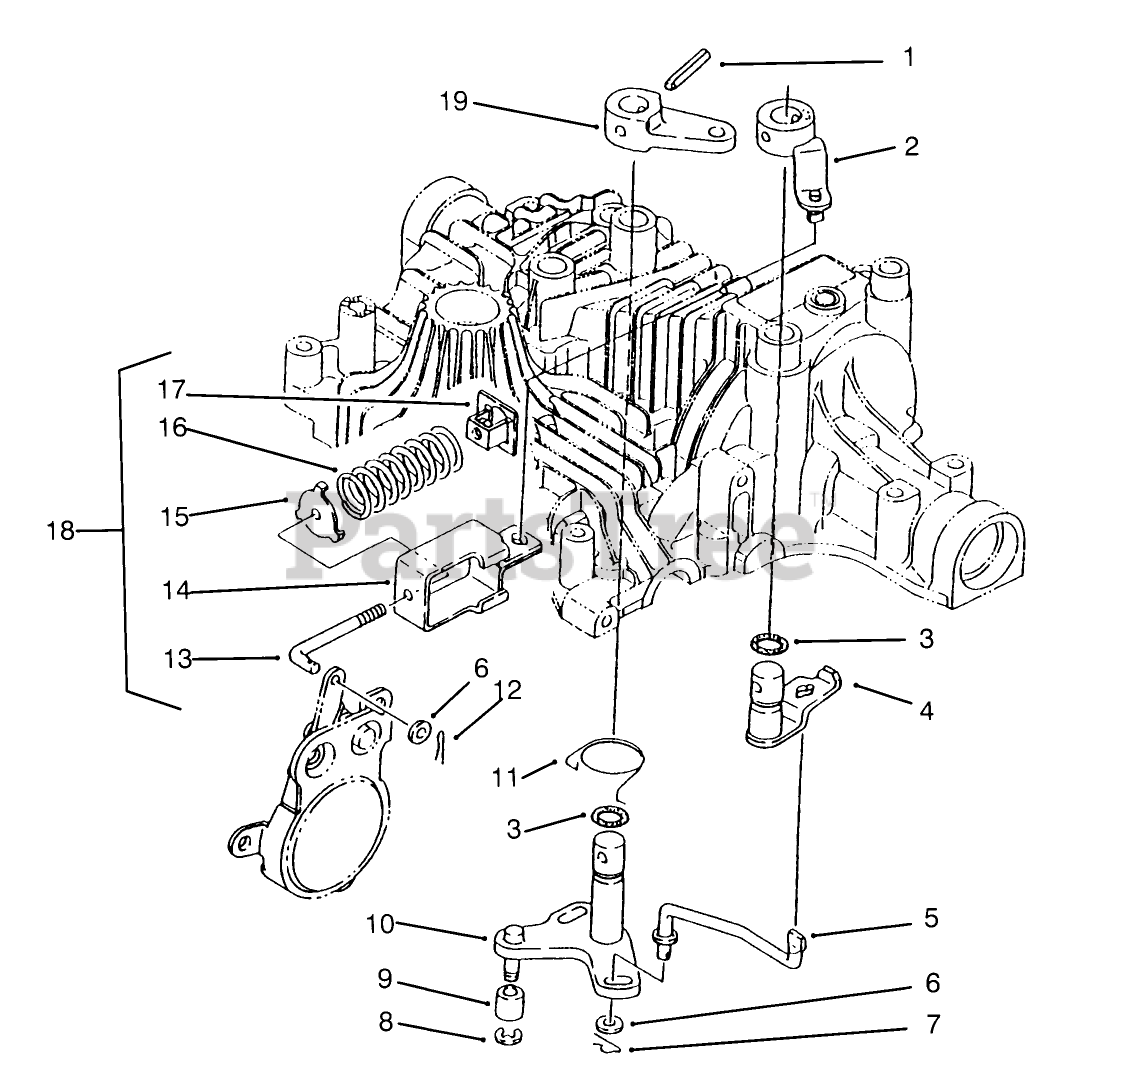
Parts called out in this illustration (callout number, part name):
1	PIN-ROLL
2	ARM-BRAKE B
3	O-RING
4	ARM-BRAKE A
5	ROD-BRAKE
6	WASHER
9	BUSHING
10	SHAFT-BRAKE
11	RETURN-BRAKE
12	PIN-COTTER
13	ROD - ADJUSTER
14	HOLDER - SPRING
15	GUIDE - SPRING
17	ADJUSTER
18	ROD ASM
19	ARM-BRAKE
